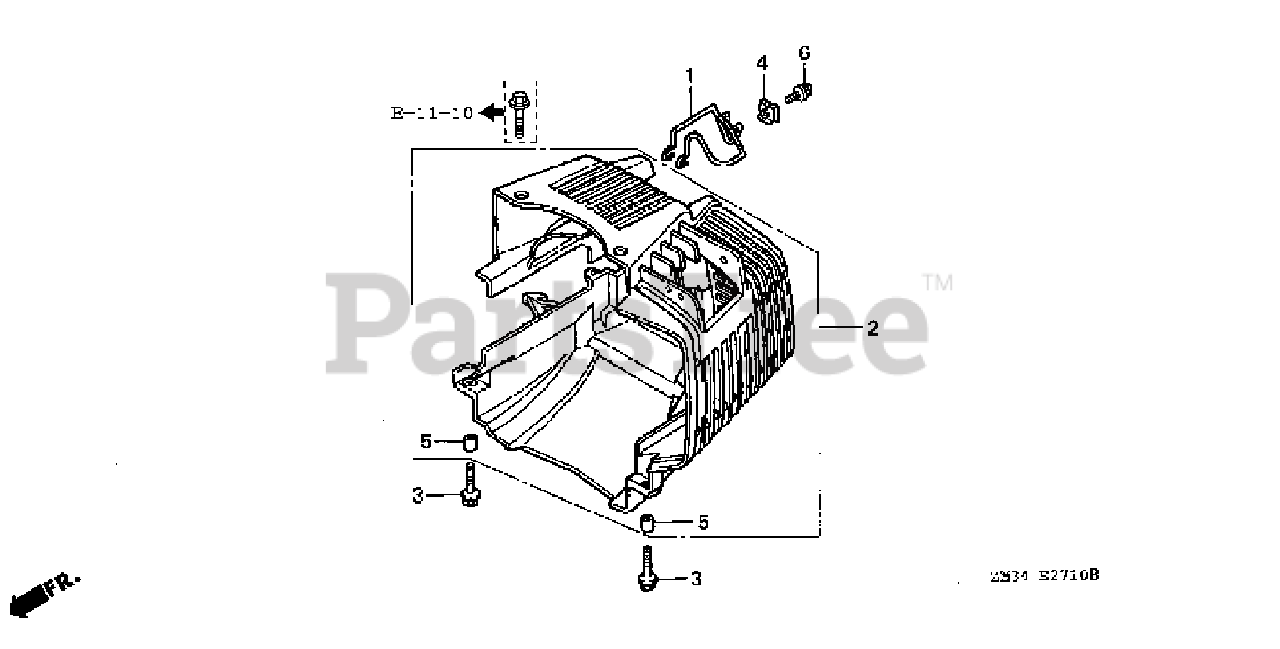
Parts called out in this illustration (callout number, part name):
1	GUARD, DEFLECTOR
2	COVER COMP., TOP
3	BOLT, FLANGE (5X22)
4	NUT, PLATE
5	COLLAR, TOP COVER
6	SCREW-WASHER (4X10)
